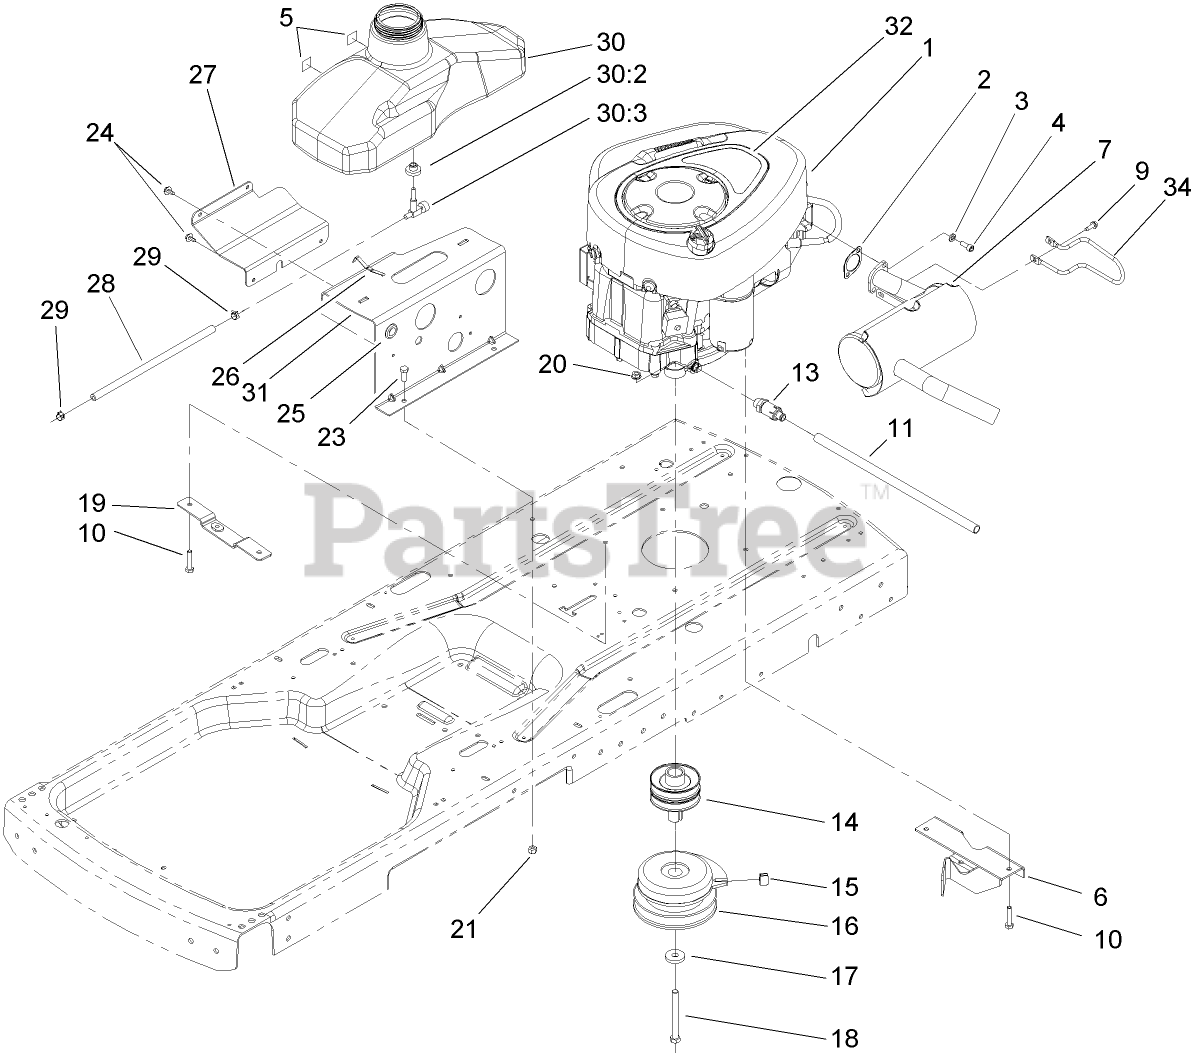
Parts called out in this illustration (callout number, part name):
1	Loose Parts Package
2	GASKET-EXHAUST
3	WASHER-LOCK
4	SCREW-HSH
5	FOAM-SWITCH, SEAT
6	BRACKET-PIVOT
7	MUFFLER
9	SCREW-HWH, THREAD ROLL
10	SCREW-HH
11	TUBE-DRAIN, OIL
13	VALVE-DRAIN, OIL
14	PULLEY-ENGINE
15	BUMPER
16	CLUTCH-PTO, ELECTRIC
17	WASHER
18	SCREW-HH
19	PLATE-MOUNT, IDLER
20	NUT-HF
21	NUT-LOCK, NI
23	SCREW-HH
24	SCREW-HHFTF
25	GROMMET
26	SPRING
27	PLATE-SUPPORT
28	HOSE-FUEL
29	CLAMP-HOSE
30	GAS TANK ASM
30:2	BUSHING
30:3	VALVE-FUEL
31	PLATE-TANK
32	DECAL-ENGINE
34	GUARD-MUFFLER
